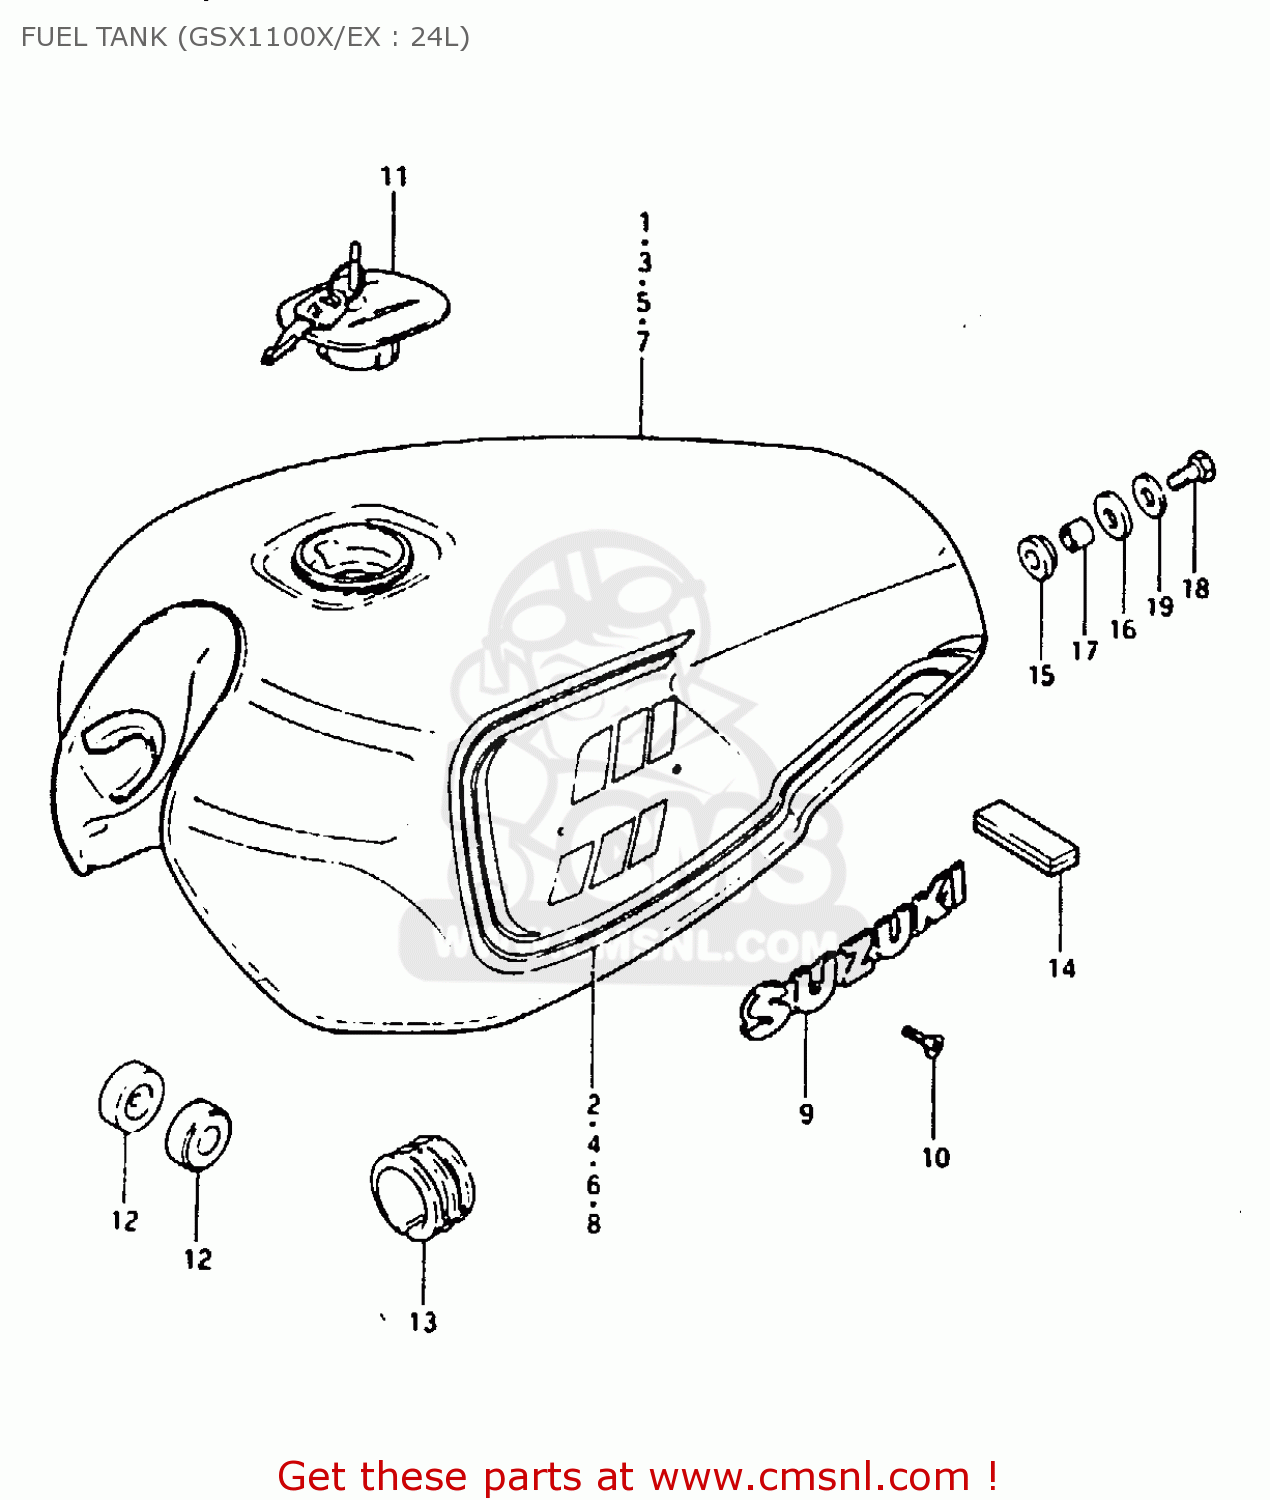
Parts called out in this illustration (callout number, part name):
1	TANK, FUEL (BLACK)
2	TAPE SET
3	TANK, FUEL (SILVER)
4	TAPE SET
5	TANK, FUEL (RED)
6	TAPE SET
7	TANK, FUEL (BLUE)
8	TAPE SET
9	EMBLEM,FUEL TANK
10	SCREW 3X6
11	CAP SET,FUEL TANK
12	CUSHION
13	CUSHION,FUEL TANK,UPPER
14	CUSHION
15	CUSHION
16	CUSHION
17	SPACER(8.5X12X19)
18	BOLT (8X30)
19	WASHER (8.5X29X1.6)
